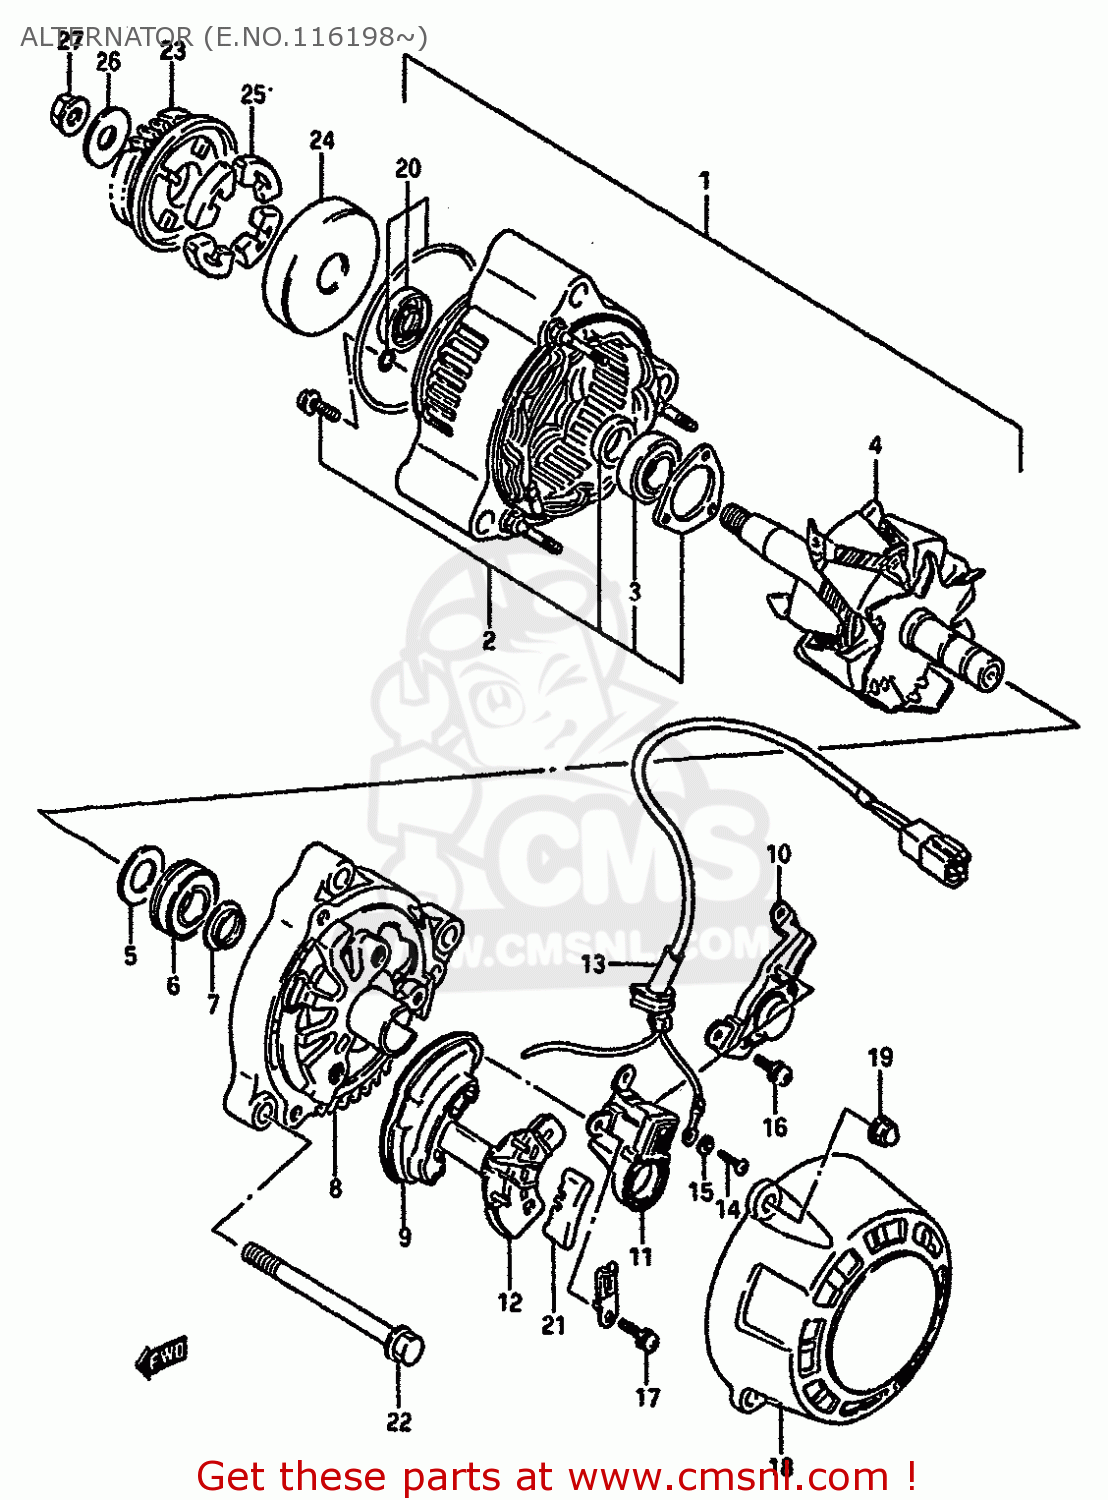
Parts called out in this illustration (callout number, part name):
1	ALTERNATOR ASSEMBLY
2	FRAME,DRIVE END
3	BEARING
4	ROTOR
5	COVER (2)
6	BALL BEARING,ALTERNATOR
7	COVER(2)
8	FRAME,END
9	HOLDER,RECTIFIER
10	REGULATOR
11	HOLDER,BRUSH
12	COVER,RECTIFIER
13	WIRE,LEAD
14	SCREW
15	LOCK WASHER
16	SCREW
17	SCREW
18	COVER
19	NUT
20	OIL SEAL SET
21	BUSH
22	BOLT (8X90)
23	GEAR,GENERATOR DRIVEN
24	HOUSING,GENERATOR GEAR
25	DAMPER,GENERATOR DRIVEN
26	WASHER
27	NUT
